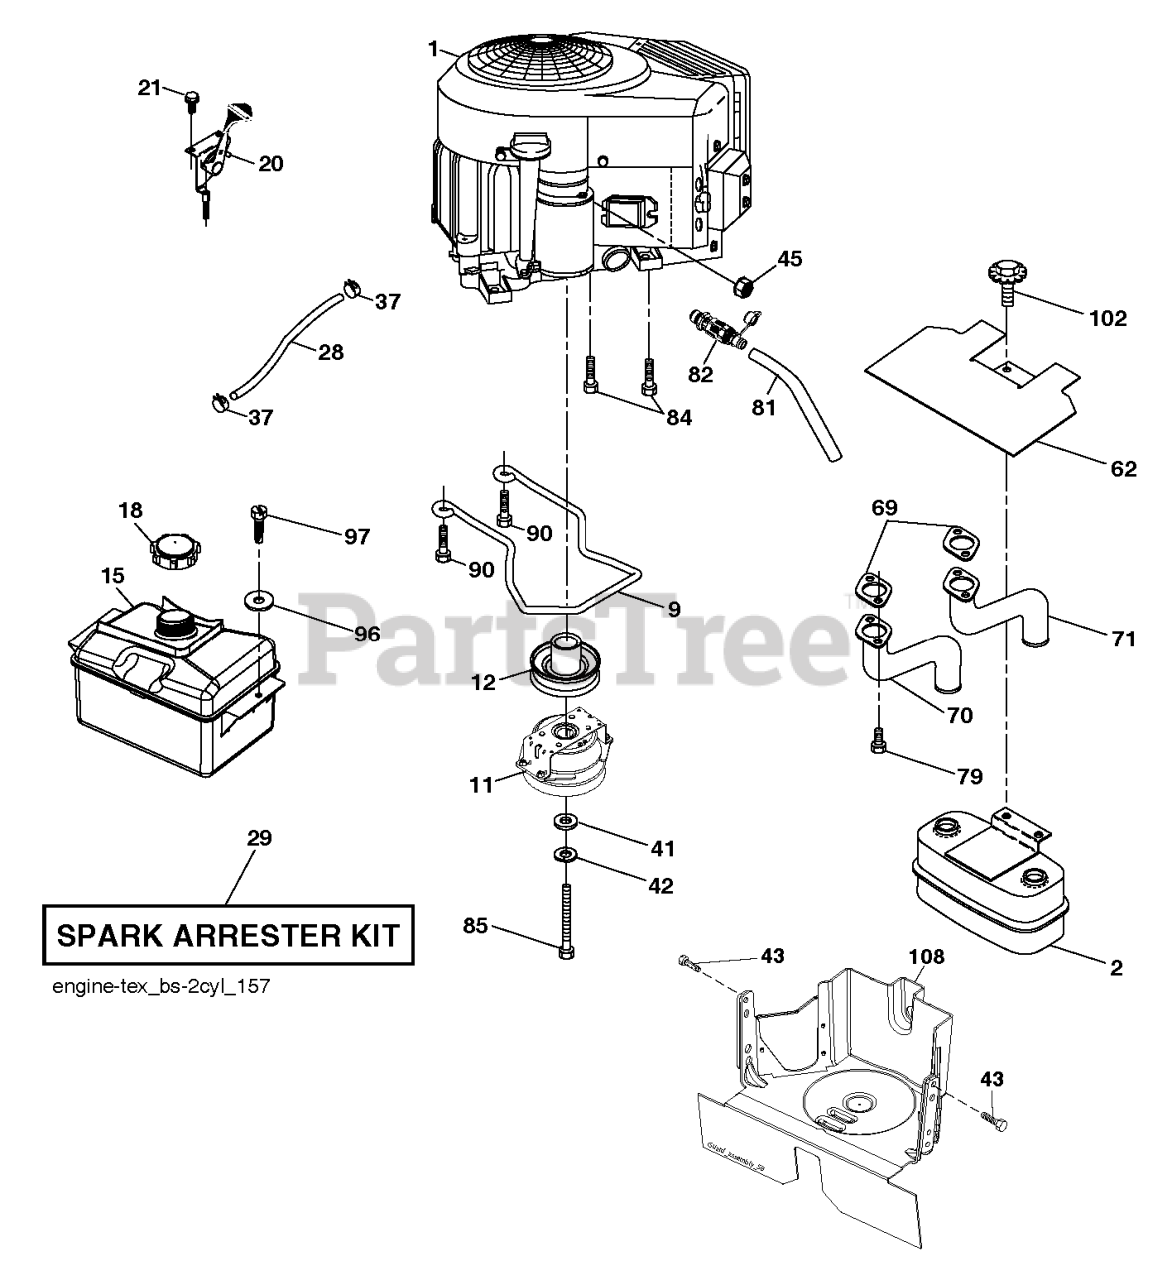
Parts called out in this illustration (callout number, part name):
2	MUFFLER.ASM.TWIN.MNTG.BRACKET
9	KEEPER.BELT.ENG.4.25"2.BLT.431
11	CLUTCH.OGURA.5.0PD.GT1.5A-EH07
12	PULLEY.ENGINE.TUFFTORQ
15	TANK.ASSEMBL.2.5GAL.NON-EPA
18	CAP ASM.FUEL.2.25"FR.
20	THROTTLE.COBRA.38"READSTART.BK
21	SCREW.#10 X 0.750.BOS
28	REPL BY 532 00 85-43
29	KIT.SPARK ARRESTOR 794945 B&S
37	HOSE CLAMP
42	WASHER 7/16 LOCK
43	SCREW 5/16-18X1
45	NUT
62	SHIELD.HEAT.MUFFLER
69	GASKET.MUFFLER
70	EXHAUST.TUBE.LH.BS/TWIN
71	EXHAUST.TUBE.RH.B&S.TWIN.INTEK
79	SCREW.SOCKET.HEAD.5/16-18
81	TUBE, DRAIN OIL ASM.
82	VALUE.OIL.DRAIN
84	SCREW.3/8-16
85	BOLT.HEX.7/16-20X3.75.GR5.RED
90	SCREW 3/8-16X1
97	SCREW HEXWSHR 1/4-20X3/4
102	SCREW
108	COVER ENGINE PULLEY COVER WITH
